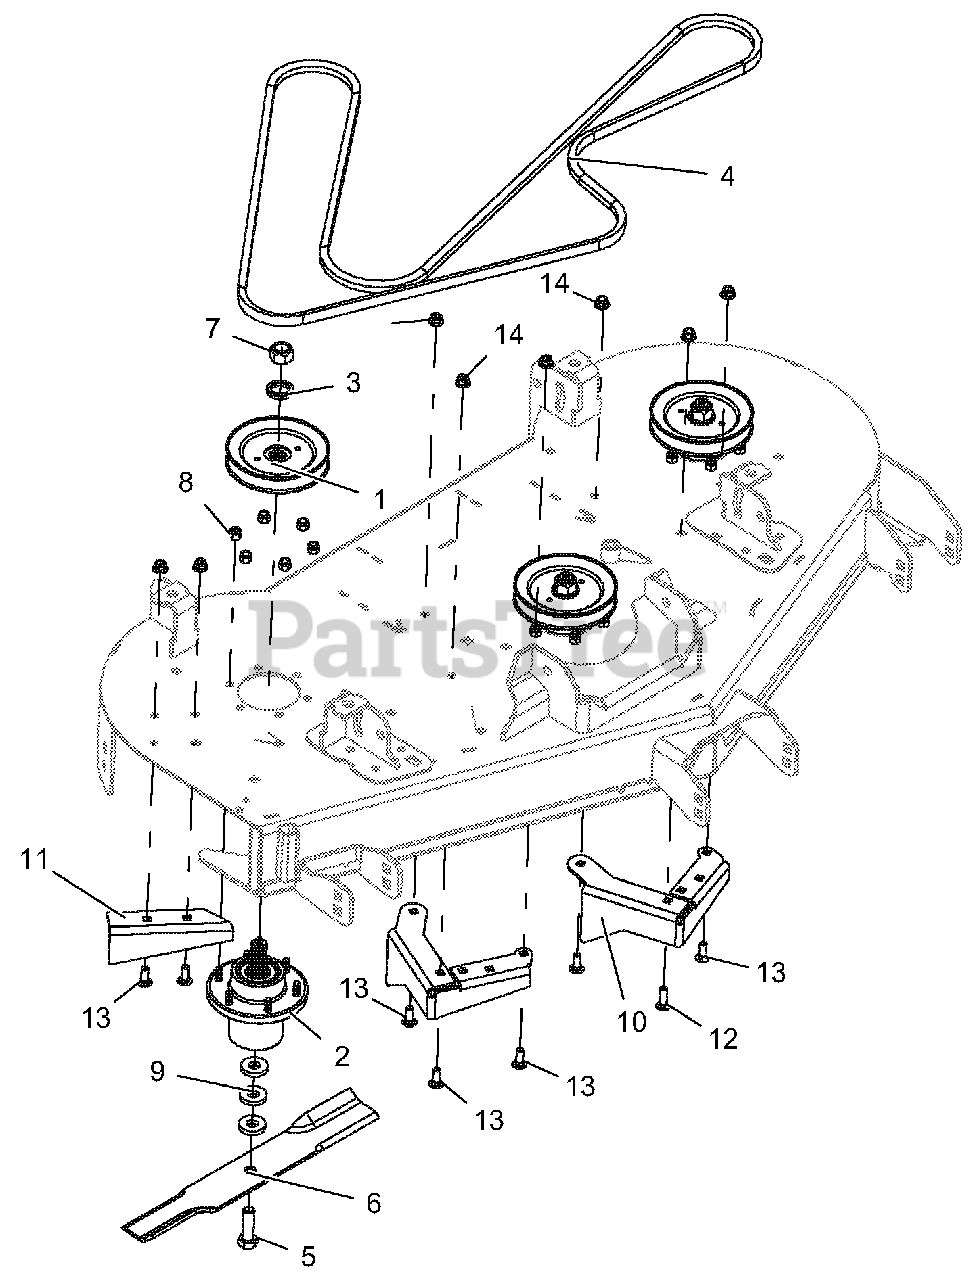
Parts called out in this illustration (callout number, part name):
1	PULLEY, SPINDLE 5.75 OD .76 HB
2	ASSY, SPINDLE HOUSING
3	SPCR, 1.005 x 1.505 x .250 PM
4	V-Belt, 5L-WRAPPED CLUTCHING
5	BLT-HEX .62-11 x 2.00 GR8 YWZC
6	BLADE, 18.000 x .80 LIFT
7	LOCKNUT, 3/4-16 CROWN GR5 Y
8	NUT-LK-NYL .38-16 YWZC
9	WSHR-FL-STL .630 x 1.50 x .25 YWZC
10	DEFLECTOR, DIRECTION
11	DISCHARGE, BAFFLE
12	BLT-RDHDSQNK .38-16 x 1.25 G5 YWZC
13	BLT-RDHDSQNK .38-16 x 1.00 G5 YWZC
14	NUT-LK-NYL-FLG .38-16 YWZC
